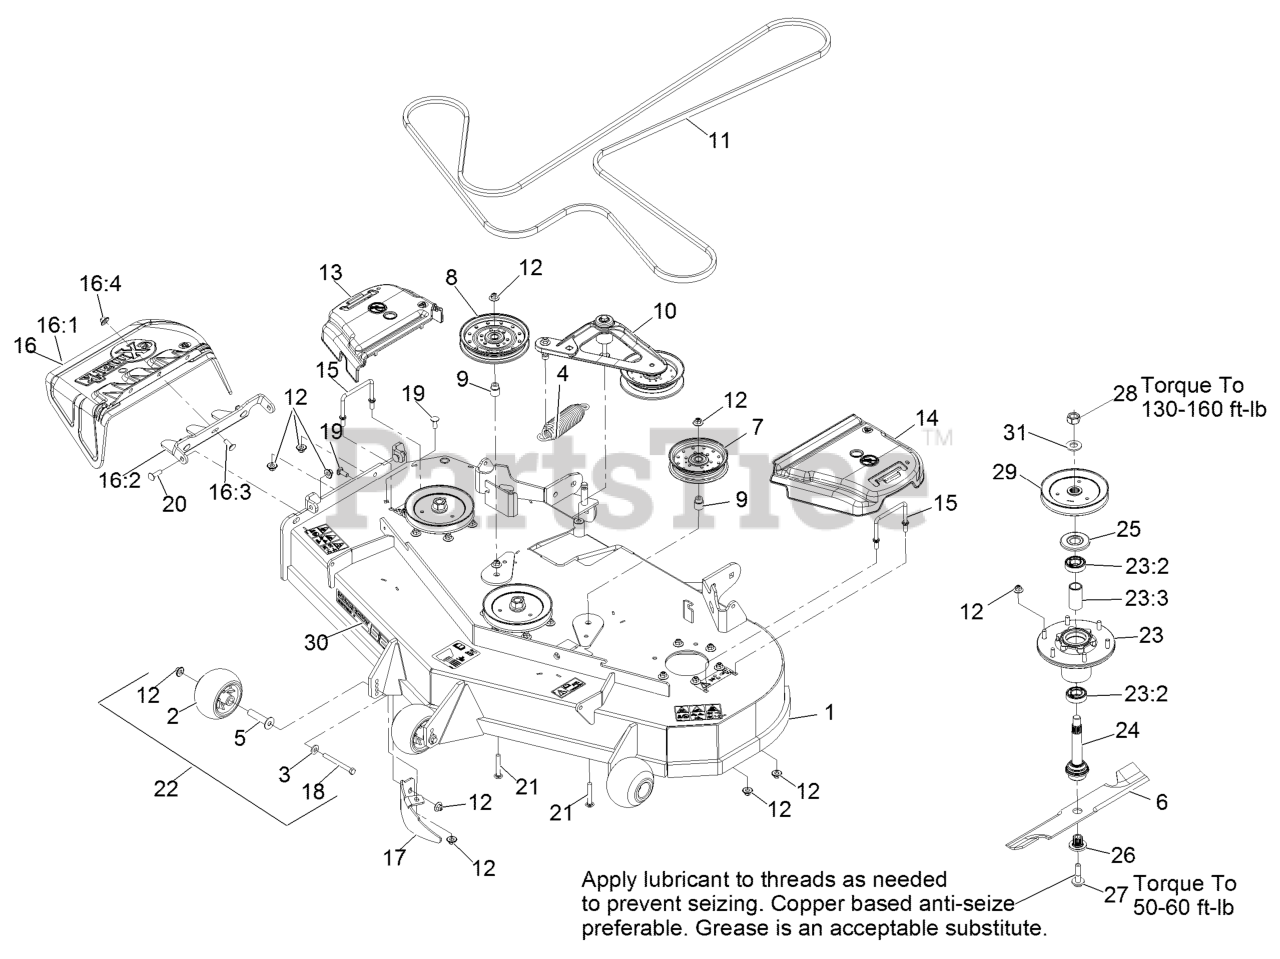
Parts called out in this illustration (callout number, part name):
1	ASM,DECK W/ DECALS 52
2	ROLLER-SCALP, ANTI
3	WASHER-BELLEVILLE
4	SPRING-EXTENSION
5	AXLE, ROLLER
9	BUSHING-IDLER
10	DECK IDLER ASM
11	BELT,V-B X 186.00"
12	Nut-Nyloc 3/8-16 Flg
13	COVER-BELT, RH
14	COVER-BELT, LH
15	WIREFORM-COVER
16	ASM,DISCHARGE CHUTE
16:1	CHUTE,DISCHARGE
16:2	BRACKET,DISCHARGE CHUTE
16:3	SCREW-CARR
16:4	Nut-Nyloc 3/8-16 Flg
17	BAFFLE-DOGLEG, LZ-VT52
18	SCREW-HH 3/8-16 X 3 3/4 GR 8
19	SCREW-CARR
20	Bolt-Carriage 3/8-16 X 1 1/4
21	SCREW-CARR
22	KIT, ANTI-SCALP ROLLER
23	ASM-CUTTER HSG WITH BEARINGS
23:2	BEARING-BALL
23:3	SPACER-BEARING
24	ASM-SPINDLE AND SEAL
25	GUARD,BEARING TOP .989
26	BUSHING,SPLINED
27	SCREW,SEMS 1/2-20 X 2.19
28	NUT-HEX
29	SHEAVE,BLADE DRIVE 6.50
30	DECAL, 524
